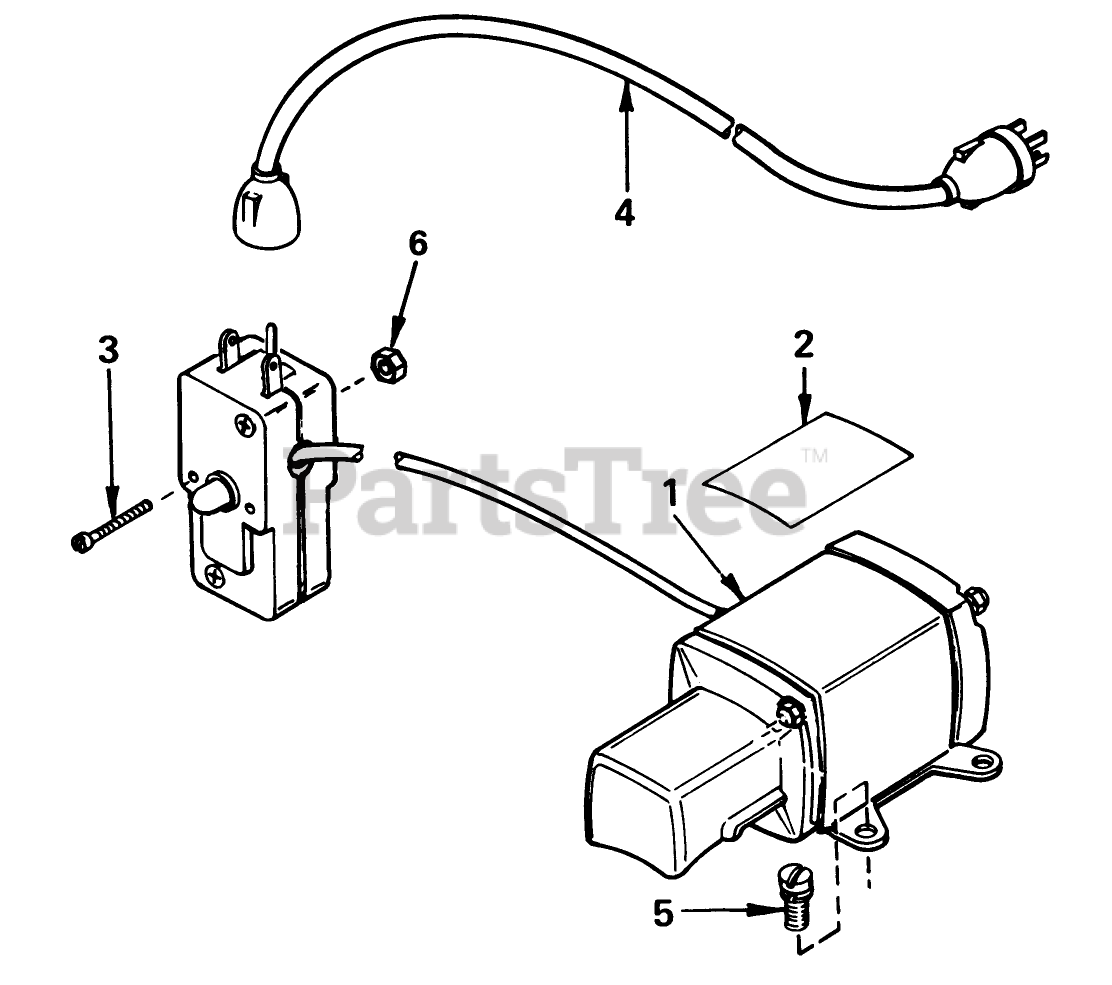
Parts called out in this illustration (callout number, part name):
1	Motor, Cranking (CSA Approved) (Incl. #2 thru 6)
2	Decal
3	Screw, Pan Hd.
4	Cord-Extension
5	Screw (T-30, 1/4-20 x 23/32)
6	Nut & Lockwasher
